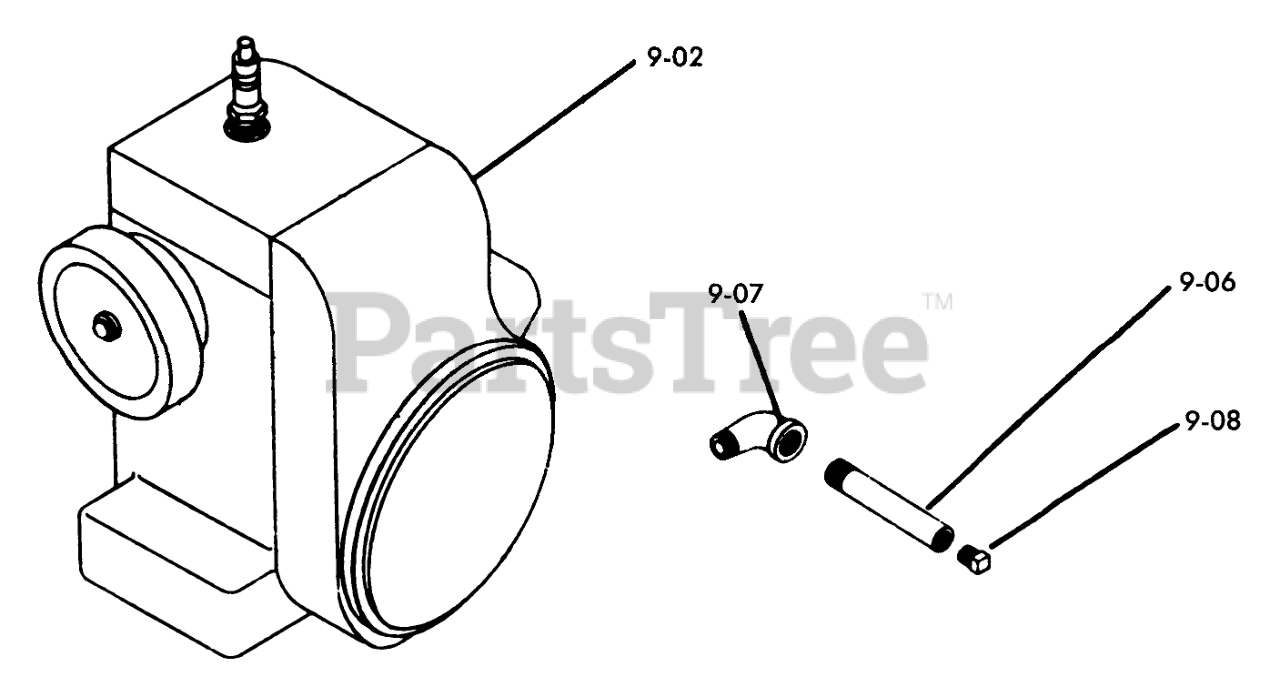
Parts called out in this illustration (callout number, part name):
9-02	Engine-16HP Kohler
9-02	BOLT
9-02	NUT
9-02	LOCKWASHER
9-02	Engine-12HP Kohler
9-06	Nipple 3/8 x 5
9-07	ELBOW-STREET
9-08	Cap
